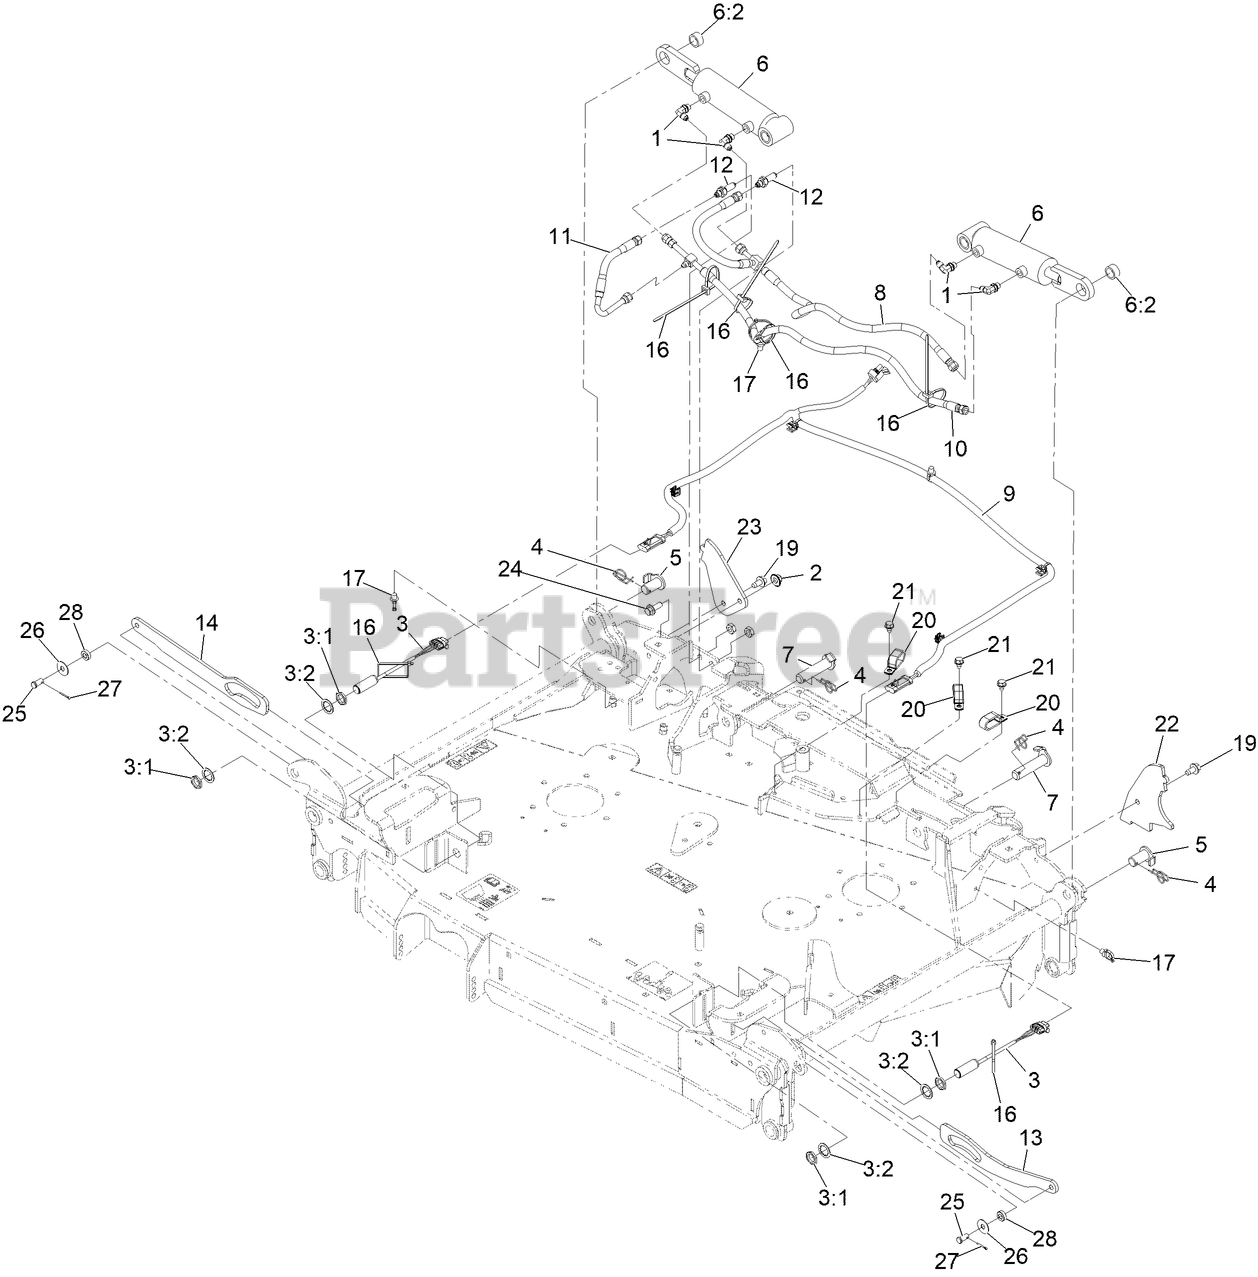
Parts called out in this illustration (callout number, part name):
1	ADAPTER,90 DEG
2	Nut-Nyloc 3/8-16 Flg
3	PROXIMITY SWITCH ASM
3:1	NUT-HEX
3:2	WASHER-LOCK, INTERNAL TOO
4	PIN-LOCKING COTTER
5	PIN-CYLINDER
6	CYL-Deck Fold
6:2	BUSHING-0.75X1.00X0.50 LONG
7	ASM-CYL PIN BASE
8	Hose ASM
9	Harness-Wire
10	Hose ASM
11	Hose ASM
12	Fiting-Straight
13	Plate-LH Flag Strap
14	Strap-RH Flag
16	TIE-CABLE
17	CLIP-TIE
19	SCREW-HWH
22	BRACKET-DECK STOP, LH
23	BRACKET-DECK STOP, RH
24	SCREW-HHF
25	PIN-CLEVIS
27	Pin-Cotter
28	BUSHING
